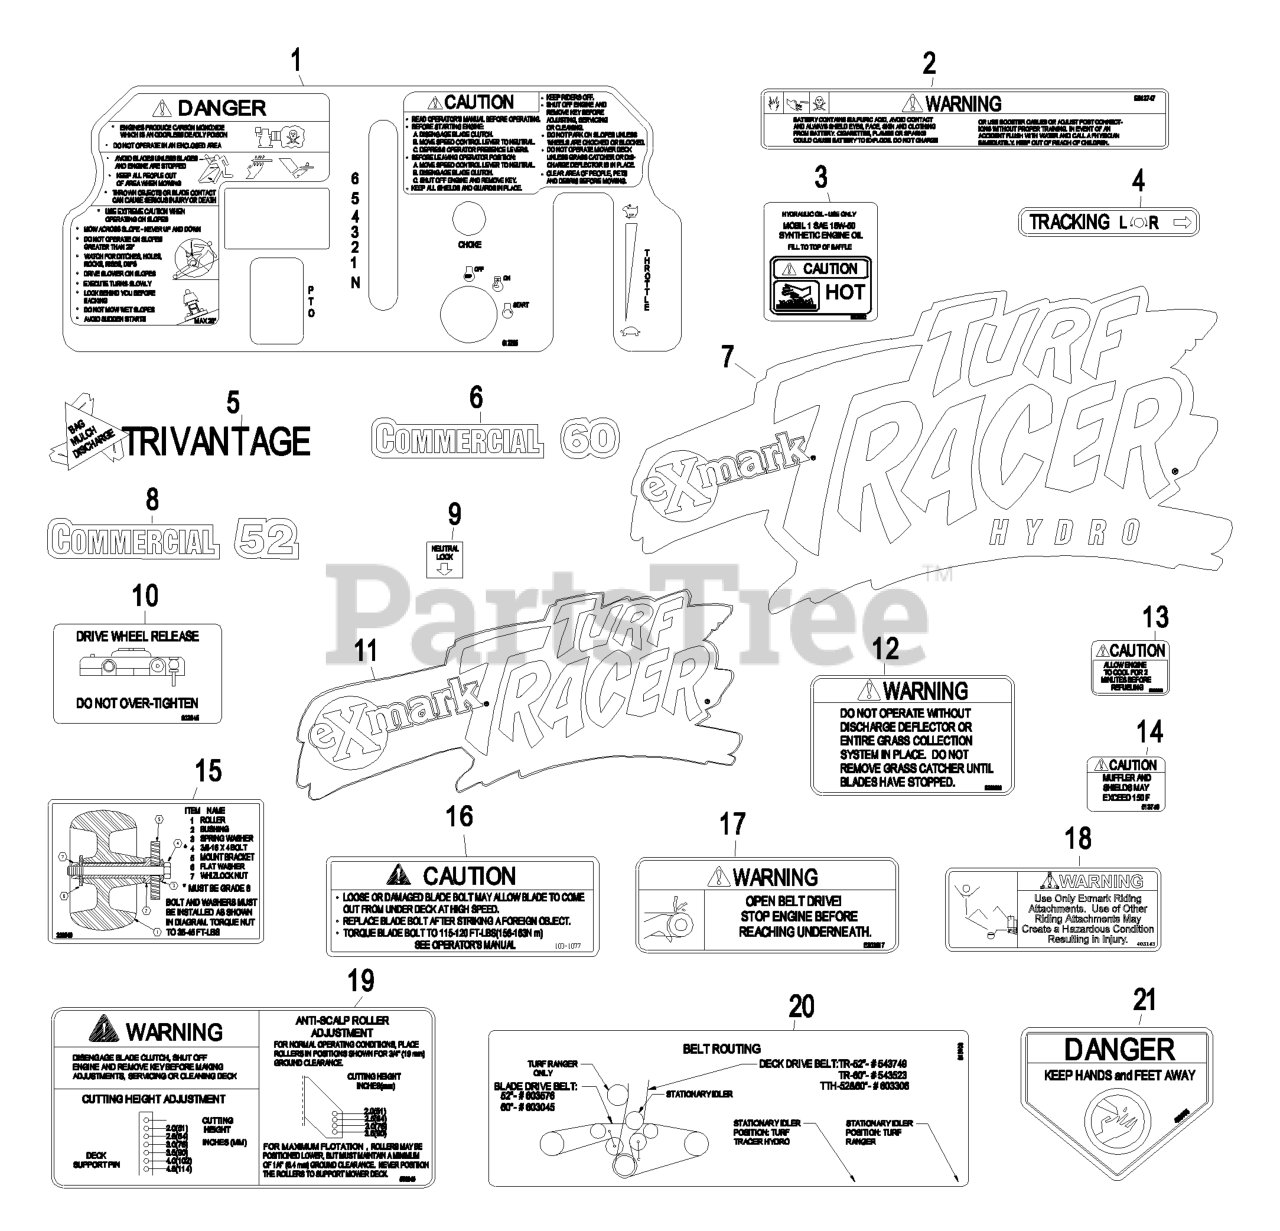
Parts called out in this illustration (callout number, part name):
2	DECAL-BATTERY
4	DECAL,TRACKING ADJUST
6	DECAL,COMMERCIAL 60
8	DECAL,COMMERCIAL 52
9	DECAL,NEUTRAL LOCK
10	DECAL,DRIVE RELEASE
12	DECAL-WARNING, DISCHARGE
15	DECAL,ROLLER MOUNTING
16	DECAL,BOLT TORQUE
17	DECAL,BELT DRIVE
18	DECAL,SULKY WARNING
19	DECAL,ANTI SCALP
20	DECAL,BELT ROUTING
21	DECAL-DANGER
